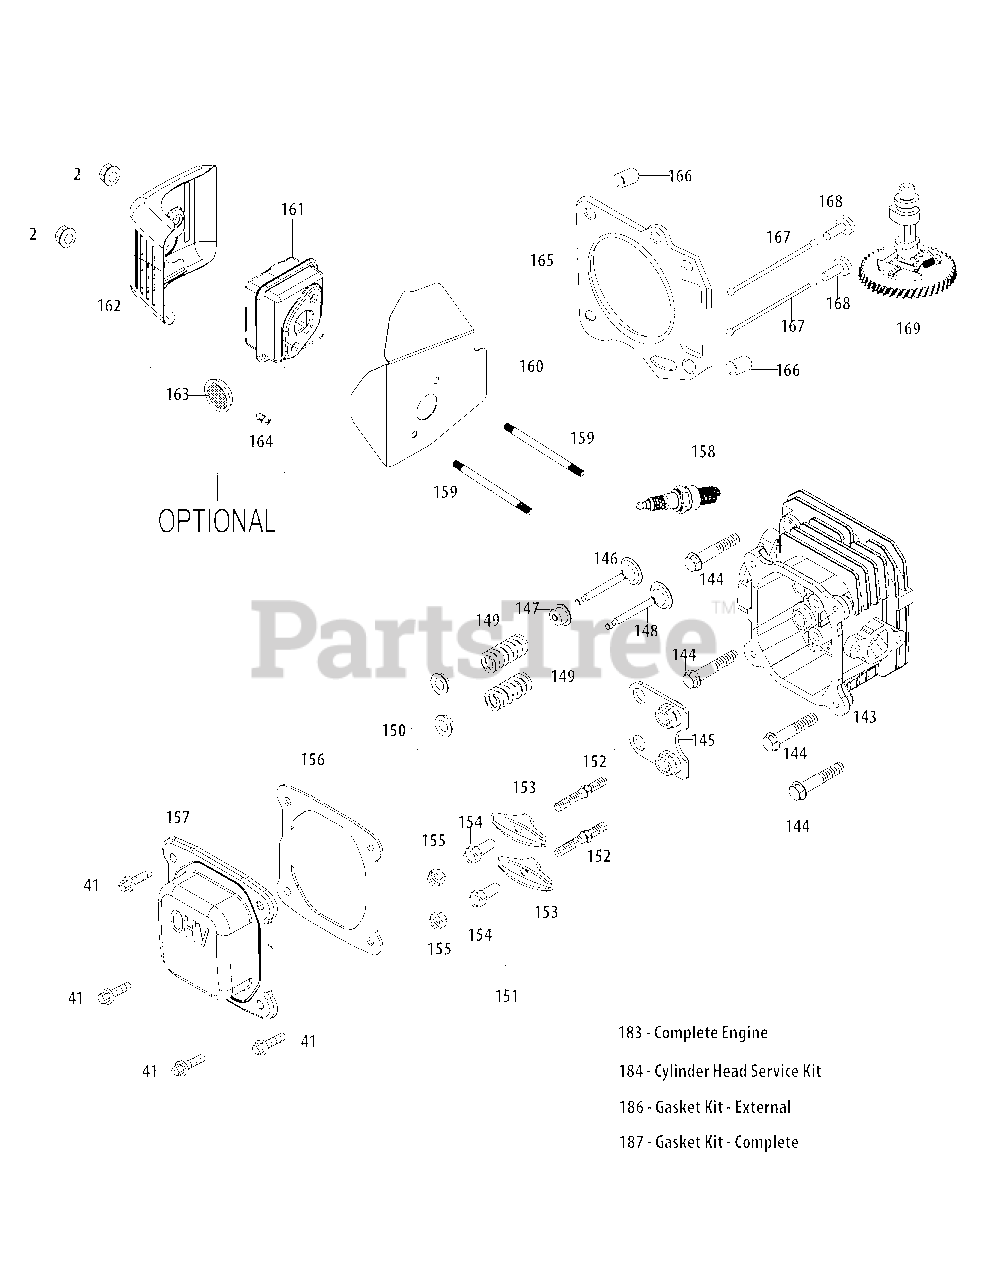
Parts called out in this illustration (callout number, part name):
2	Nut M6X10M
41	Bolt M6X14 Multi-Purpose
143	Cylinder Head
144	Bolt M8X54 Cylinder Head
145	Push Rod Guide
147	Intake Valve Seal
149	Valve Spring
150	Valve Spring Retainer
151	Rocker Arm Assembly
152	Rocker Arm Stud
153	Rocker Arm
154	Fulcrum Nut
156	Valve Cover Gasket
157	Valve Cover
158	Spark Plug
159	Muffler Stud M6X68
159	Muffler Stud Assy
160	Muffler Gasket
161	Muffler Assembly
162	Muffler Shield
163	Spark Arrestor
164	Spark Arrestor Screw
165	Cylinder Head Gasket
166	Cylinder Head Dowel Pin 10×16
169	Camshaft Assembly
183	Complete Engine
184	Cylinder Head Svc Kit
186	Gasket Kit - External
187	Gasket Kit - Complete
